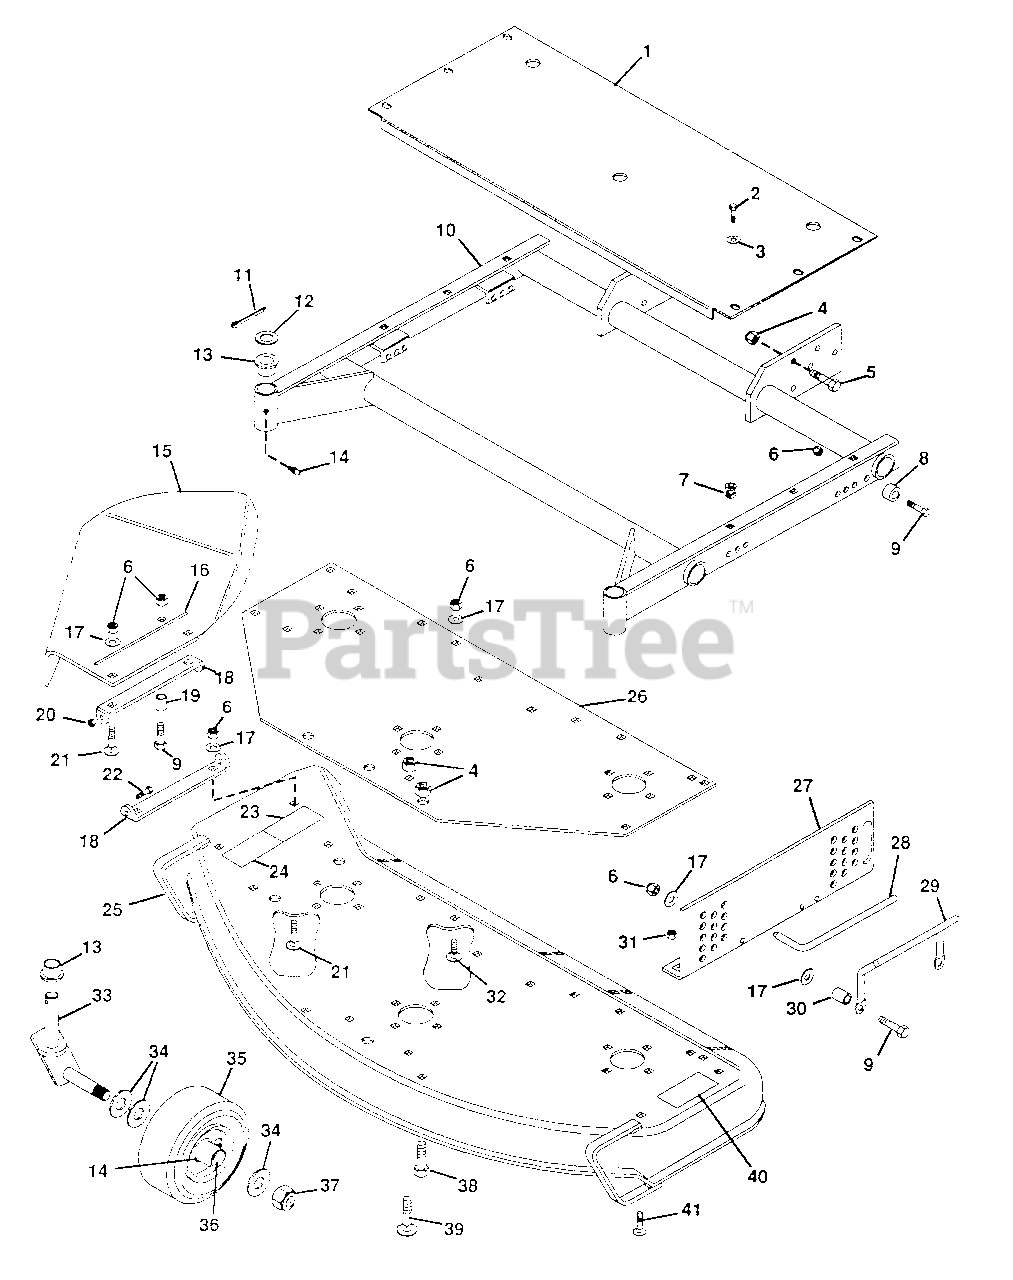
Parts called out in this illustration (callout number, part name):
1	Guard, 50" PMH Series
2	Screw, 1/4-20x.50 Self Tapping
3	Washer, Flat .281x.625x.065
4	Nut, Lock 1/2-13
5	Bolt, Hex 1/2-13x1.50
6	Nut, Lock 3/8-16
7	Grommet, Plastic
8	Bushing .391x.622x.670
9	Bolt, Hex 3/8-16x1.50
10	Weldment, Mower Frame
11	Pin, Cotter .187x1.50
12	Race, Bearing Thrust
13	Bushing, Pivot
14	Fitting, Lube 1/4-28
15	Shield, Safety Ext. 50" Mower
16	Stripe
17	Washer, Flat .406x.812x.065
18	Bracket, Chute
19	Stop, Chute
20	Nut, Lock 1/4-20
21	Bolt, 3/8-16x1.00 Rd Hd Sq Nk
22	Bolt, Hex 1/4-20x.875
23	Decal, Danger Hand
24	Decal, Warning Eye
25	Weldment, 50" Mower Deck
26	Plate, Support
27	Bracket, Mower Side Support L.H.
27	Bracket, Mower Side Support R.H.
28	Pin, Mower Locking
29	Handle
30	Bushing
31	Nut, Lock 5/16-18
32	Bolt, Carriage 3/8-16x.75
33	Weldment, Caster Fork
34	Washer, Flat .812x1.496x.134
35	Wheel, Gauge
36	Bearing, Gauge Wheel
37	Nut, Lock 3/4-10
38	Bolt, Hex 1/2-13x1.25
39	Bolt, 1/2-13x1.00 Rd Hd Sq Nk
40	Decal, Danger Foot
41	Bolt, Carriage 5/16-18x1.00
